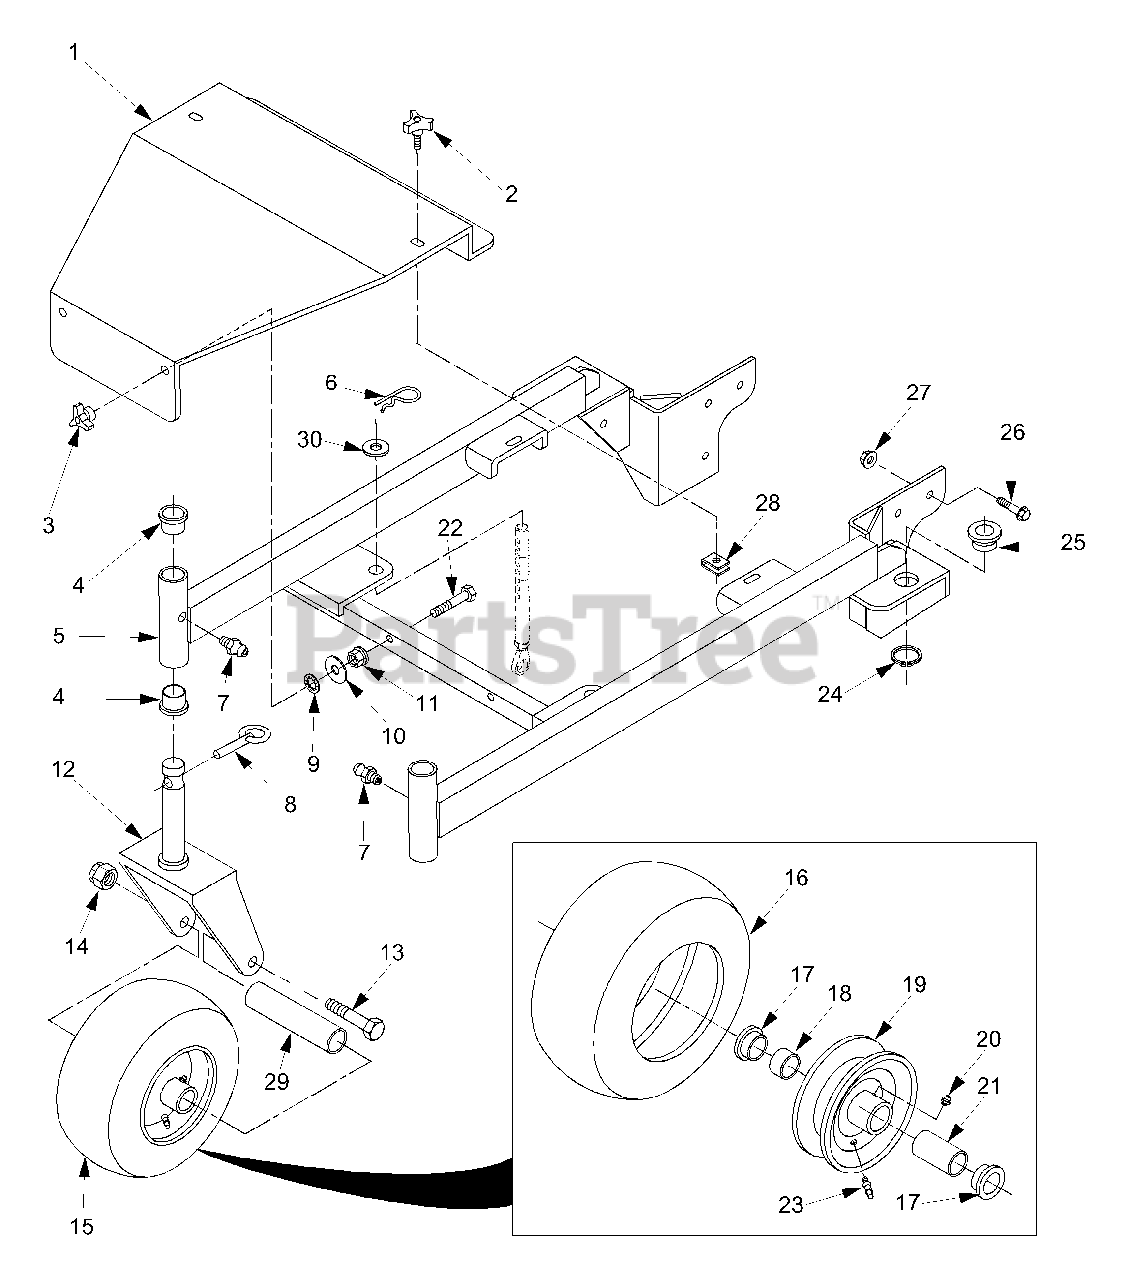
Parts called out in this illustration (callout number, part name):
1	Belt Cover With Decal
2	Knob With Stud
3	Knob, Deck Cover Mounting
4	Bushing, Caster
5	Frame Weldment, Deck Mounting - 36"
6	Hair Pin Cotter, .177 x 3.25"
7	Grease Fitting Str. 1/4-28 Self Tap
8	Quick Pin .438 Dia
9	Nut, Push-On - 3/8 Thd.
10	Flatwasher, 3/8 - (.391 x .938 x .105)
11	Nut, 3/8-16 Serrated Flange Hex Head
12	Yoke, Caster Wheel
13	Capscrew, Hex Head 1/2-13 x 6.50"
14	Locknut, 1/2-13 Elastic Stop
15	Wheel Assembly, Caster
16	Tire, 11 x 4.00-5
17	Retainer
18	Roller Bearing
19	Rim, 5.0 x 2.75 With Zerk & Valve
20	Grease Fitting Str.1/4-28
21	Roller Bearing .625 x 3.25"
22	Capscrew, Hex Head 3/8-16 x 2.25"
23	Tire Valve
24	Retaining Ring 1.50 Ext.
25	Bushing, Deck Adjustment Pin
26	Capscrew, Hex Head 7/16-14 x 1.0"
27	Nut, 7/16-14 Serrated Flange Hex
28	U-Nut, 3/8-16
29	Sleeve, Caster Wheel
30	Flatwasher, 5/8 - (.688 x 1.75 x .134)
